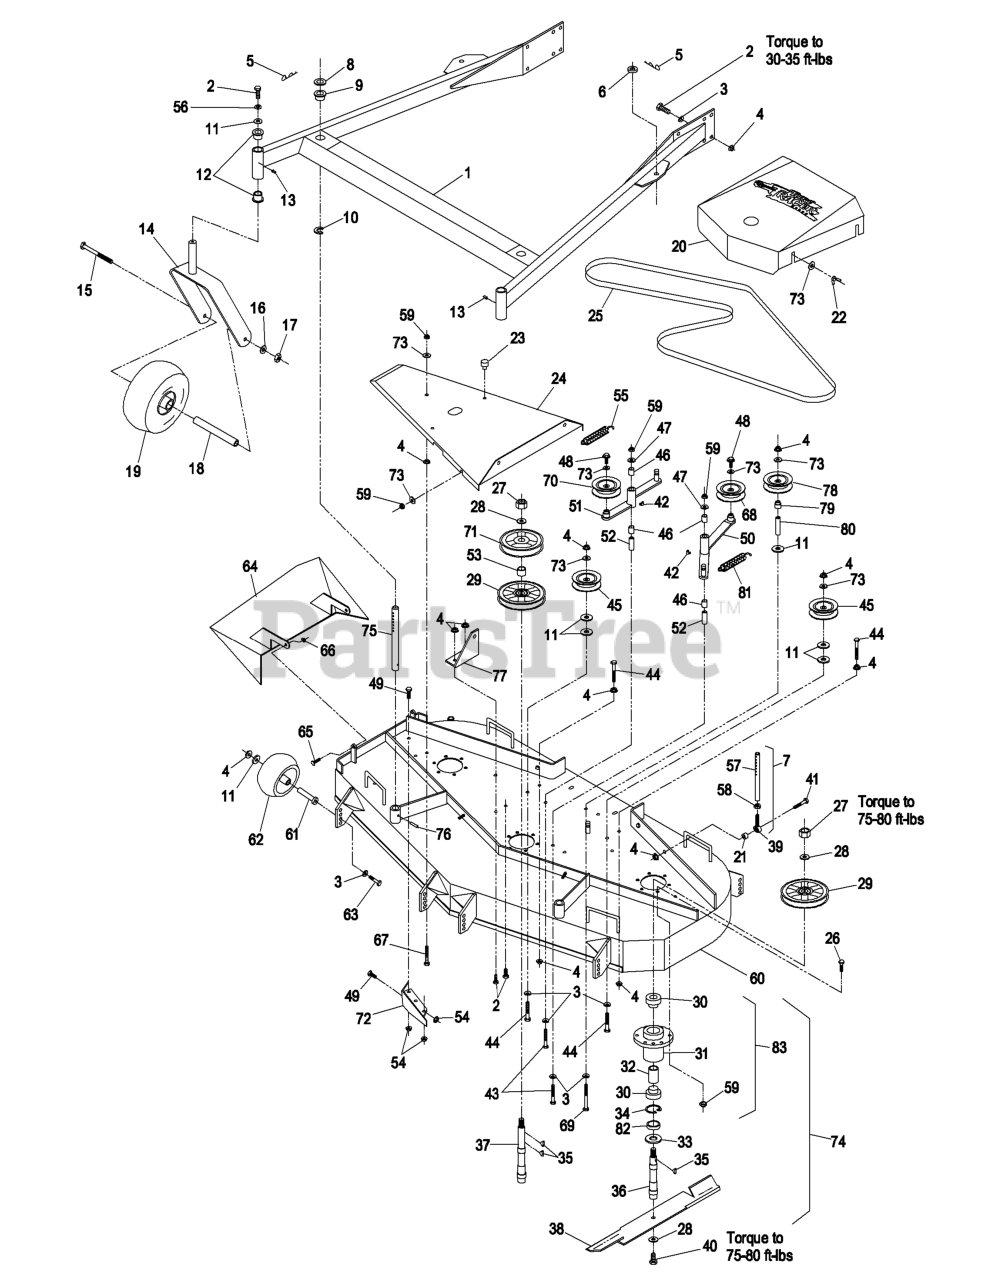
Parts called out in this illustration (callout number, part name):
1	SUPPORT ASSY-FMD60
5	PIN,HAIR COTTER
8	SPACER-DECK SUPPORT
9	BUSHING-DECK
11	WASHER
12	BEARING-FLANGED
22	NUT-WING
24	WLD,DECK COVER
25	BELT-DRIVE, BLADE
28	WASHER-SPRING
29	SHEAVE,BLADE DRIVE
30	BEARING
32	SPACER-BEARING
33	GUARD-BEARING, BOTTOM
36	SHAFT,SPINDLE SHORT
37	SHAFT,SPINDLE LONG
39	BALLJOINT
43	SCREW-HH
45	IDLER,PULLEY
46	SLEEVE-BEARING
50	Arm, Deck Drive Idler
51	Arm, Deck Idler
52	BUSHING-PIVOT, IDLER
53	SPACER-TUBE
55	SPRING-EXTENSION
57	LINK,SUPPORT
61	BUSHING-ROLLER
62	ROLLER-SCALP, ANTI
68	PULLEY-IDLER
70	IDLER,PULLEY
72	WLD,BAFFLE DISCHARGE
74	CUTTER HOUSING ASM,OUTER
75	ROD,DECK SUPPORT
77	BRACKET,SPRING ANCHOR
78	PULLEY-IDLER
79	BUSHING,IDLER
80	SPACER-FENDER
81	SPRING-EXTENSION
82	SPACER-PULLEY/BEARING
